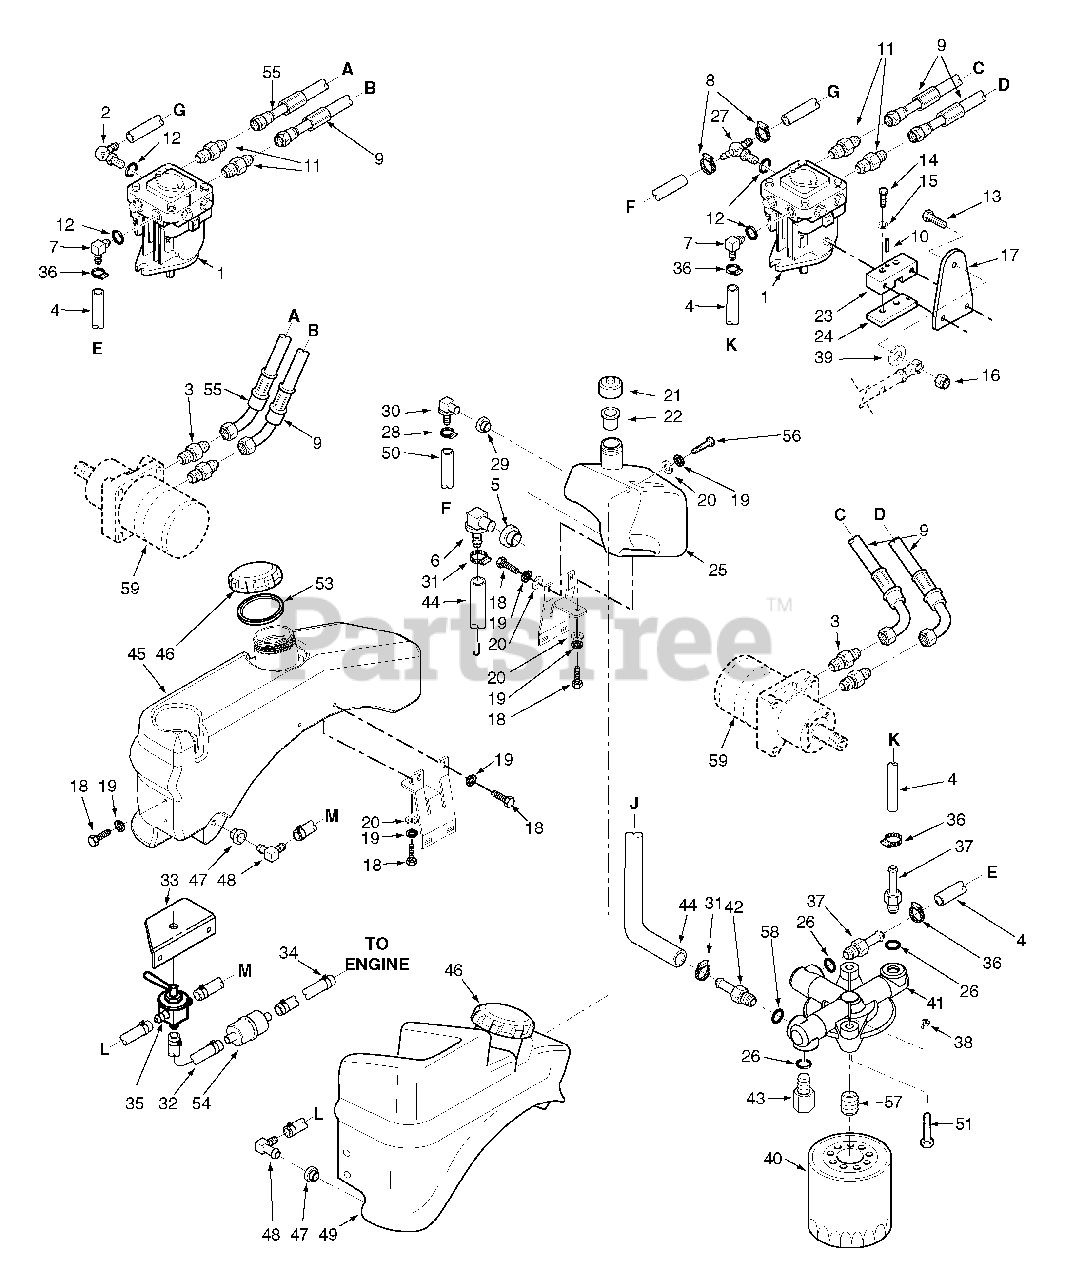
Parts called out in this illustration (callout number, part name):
1	Pump, BDP-10A-316 (L.H.)
2	Elbow, 90 Degree 9/16 O-Ring x 3/8 Hose
3	Fitting, 1/2" JIC x 5/8 O-Ring
4	Hose, 3/8 Pushlock (Specify length)
5	Bushing
6	Fitting
7	Elbow, 90 Degree 9/16 O-Ring x 3/8 Hose
8	Hose Clamp, .69 Dia.
9	Hose Assembly
10	Roll Pin
11	Fitting, 1/2" JIC x 1/2" O-Ring
12	O-Ring
13	Bolt, Hex Head 3/8-16 x 1-1/2"
14	Bolt, Hex Head 1/4-20 x 1-1/4"
15	Lockwasher
16	Nut, Elastic Stop 3/8-16
17	Control Lever
18	Bolt, Hex Head 5/16-18 x 3/4"
19	Lockwasher, 5/16
20	Flatwasher, 5/16-.375 x .875 x .083
21	Cap, Hydraulic Tank
22	Insert, Filler Neck
23	Control Block
24	Clamp Plate
25	Hydraulic Tank Assembly w/fittings
26	O-Ring, 9/16"
27	Tee Fitting, O-Ring to Barb
28	Clamp, .69 Max. / .25 Min. Dia.
29	Bushing
30	Elbow, 0.38 Hose
32	Fuel Hose, 1/4 ID
33	Bracket Fuel Valve
34	Clamp, Fuel Hose 1/4 Hose ID
35	Valve, Fuel Shutoff
36	Clamp, .69 Max. / .25 Min. Dia.
37	Fitting, 9/16 O-Ring x 3/8 Hose
38	Nut, Serr. Flange 5/16-18
39	Flatwasher, 3/8-.391 x .938 x .105
40	Oil Filter
41	Filter Head Assembly
42	Fitting, 3/4 O-Ring x 3/8 Hose
43	Plug, 9/16-18 O-Ring
44	Hose, Filter Inlet
45	Fuel Tank RH
46	Cap, Fuel Tank
47	Tank Bushing
48	Elbow, 90 Degree
49	Fuel Tank LH
50	Hose, 3/8 Pushlock 15" Long
51	Bolt, Hex Head 5/16-18 x 2"
52	Screw, 1/4-20 x 2"
53	Gasket, Gas Tank Cap
54	Fuel Filter
55	Hose Assembly
56	Bolt, Hec Head 5/16-18 x 1-1/2
57	Nipple, Oil Filter 1.0-12 UNF-2A x 1-1/4"
58	O-Ring, 3/4"
59	Wheel Motor, Hydro-Gear
